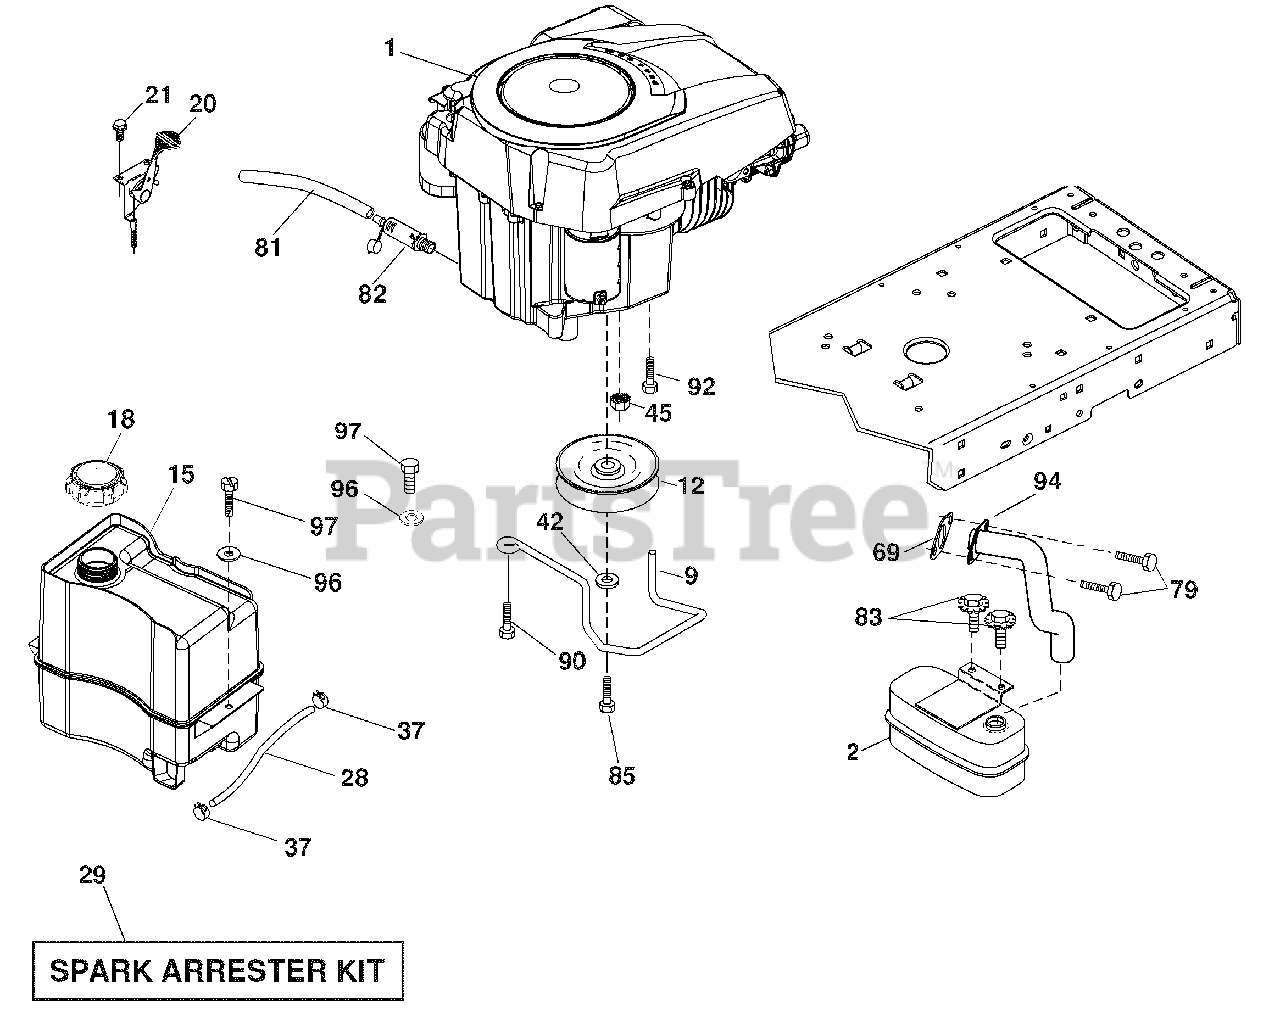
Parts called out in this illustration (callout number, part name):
9	Keeper Belt Engine
12	Pulley Engine
15	Tank Fuel
18	Cap Asm
20	Control Throttle
21	Screw 10 x 3/4 Single Lead Hex
28	Fuel Line
29	Spark Arrester Kit
37	Clamp Hose
42	Washer Lock 7/16
45	Nut Keps Hex 1/4-20 unc
79	Screw Socket Head 5/16-18 x .75
81	Tube Drain Oil Easy
82	Plug Drain Oil
83	Bolt 5/16-18 UNC x 3/4 w/Sems
85	Bolt Hex 7/16-20 x 4 x Gr. 5-1.5 Thr
90	Screw 3/8-16 x 1
92	Screw 3/8-16 x 1
94	Tube Exhaust
96	Washer 9/32 x 7/8 x 16 Ga.
97	Screw 1/4-20 x 3/4
